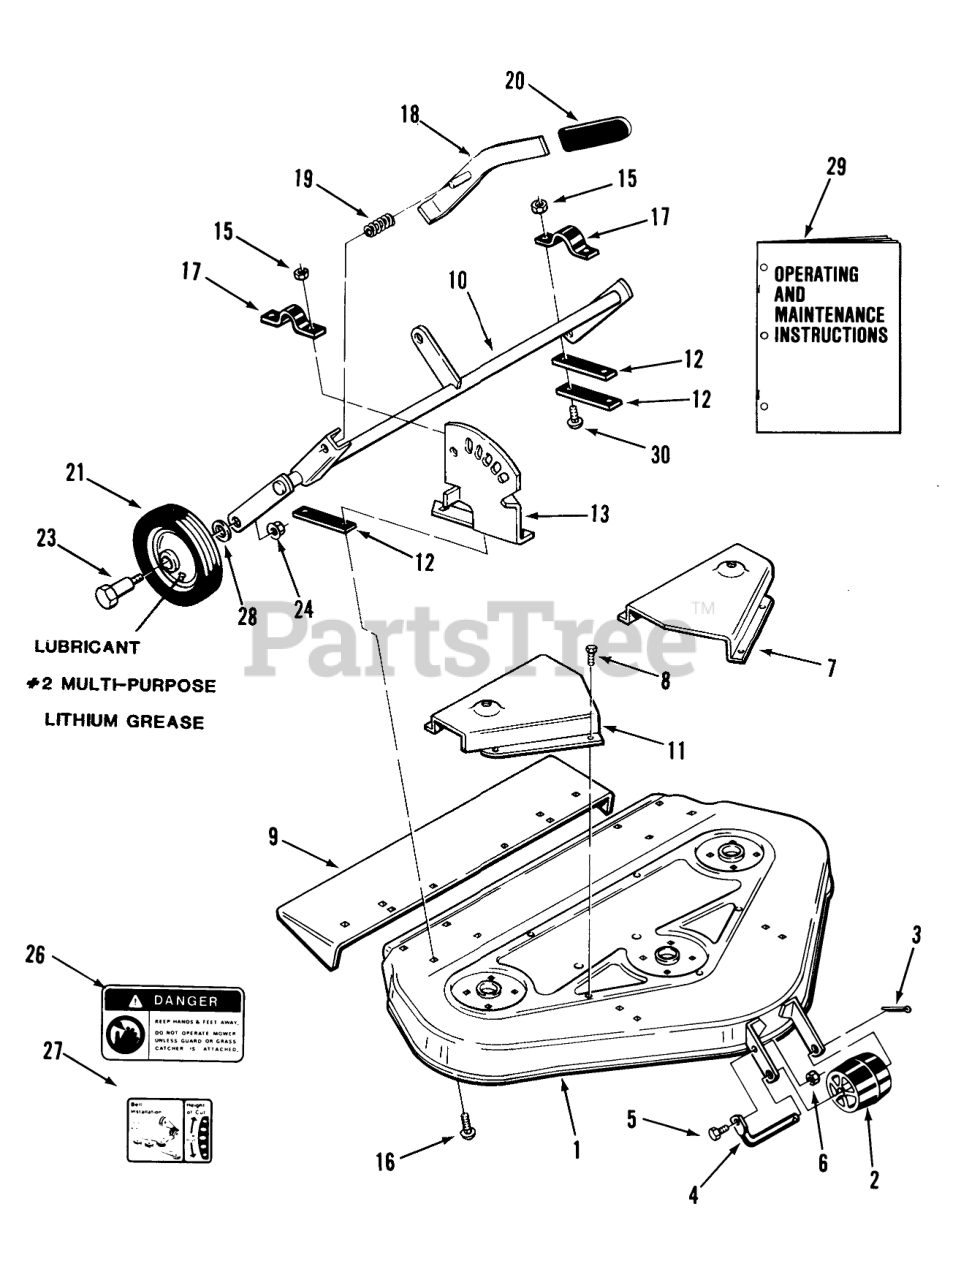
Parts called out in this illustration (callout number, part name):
1	Mower Deck
2	Roller
3	Cotter Pin
4	Roller Shaft
5	H H C S
6	Nut
7	Cover-Belt
8	SCREW -4
9	Chute Extension
10	Gage Wheel Support
11	Belt Cover RH
12	Bar
13	Quadrant
15	Nut
16	Bolt
18	Lever
19	SPRING-COMPRESSION
21	WHEEL
23	BOLT-SHOULDER
24	Nut
26	Danger Decal
27	DECAL-HEIGHT & BELT
28	WASHER
29	Manual-Operators
30	Bolt
